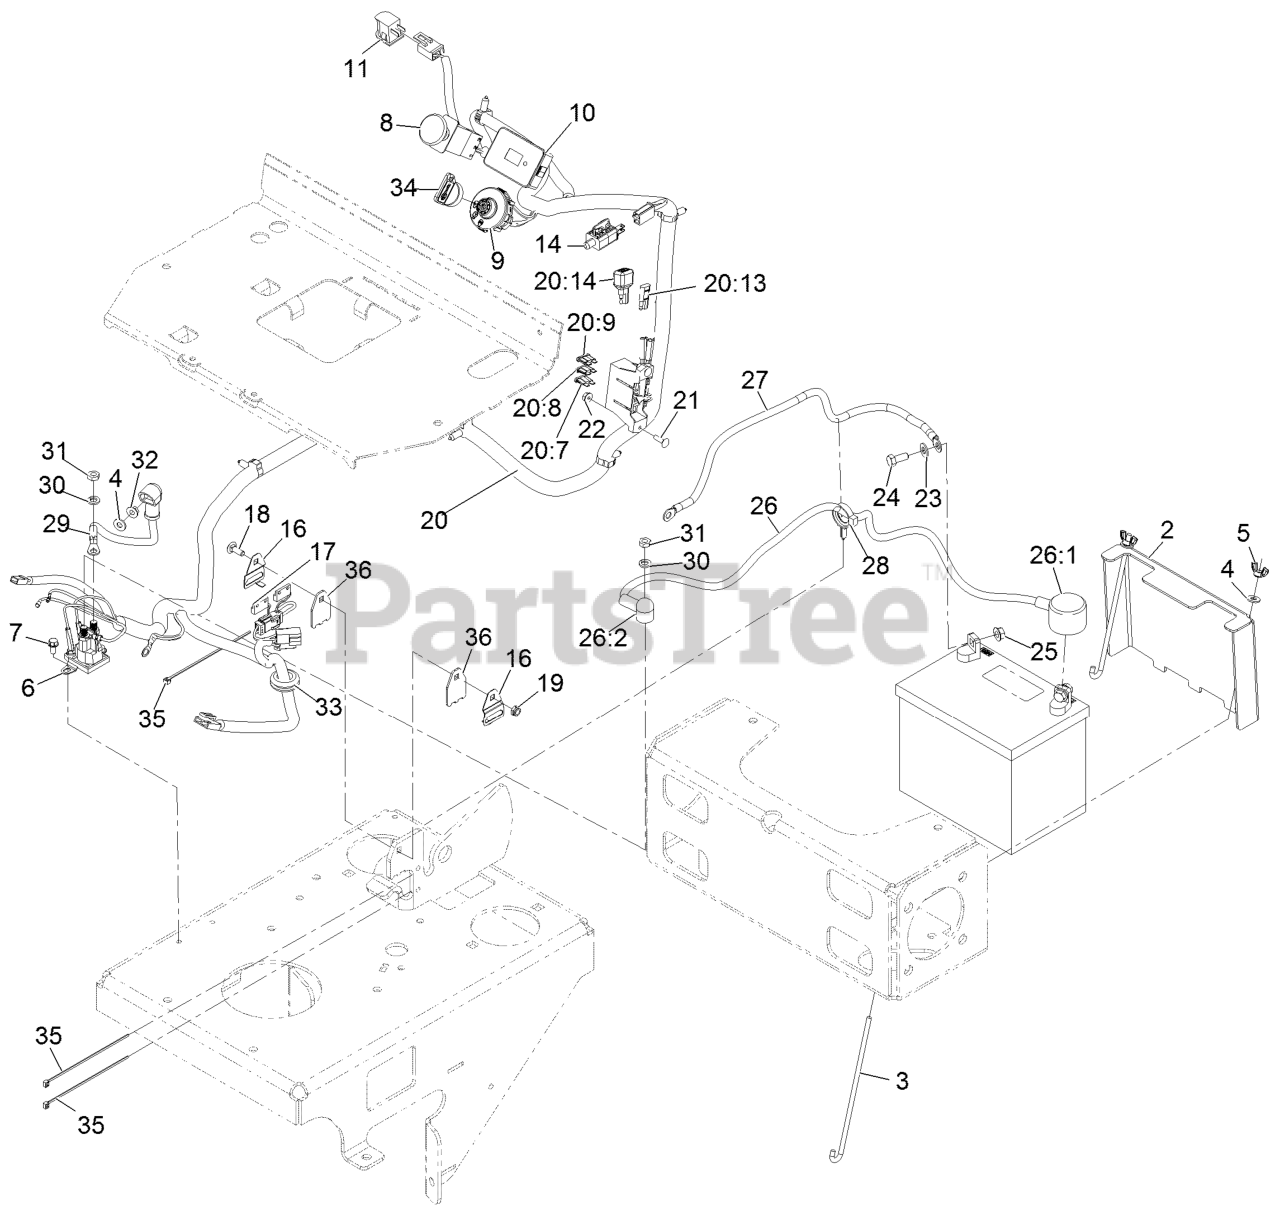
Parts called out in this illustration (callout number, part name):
2	COVER-BATTERY
3	BOLT-HOLDDOWN
4	WASHER-FLAT
5	WINGNUT
6	SOLENOID
7	SCREW-HWH
8	SWITCH-PTO, ON-ON
10	MODULE-HOUR METER
11	SWITCH-BAIL
14	SWITCH-PLUNGER, NC, SPST
16	CLAMP-SWITCH
17	HARNESS-SWITCH, REED
18	BOLT-CARR
19	NUT-LOCK, NI
20:7	FUSE-BLADE, 30 AMP
20:8	FUSE-BLADE, 25 AMP
20:9	FUSE-BLADE, 10 AMP
20:13	CAP-PLUG
21	SCREW-CARR
23	WASHER-PLAIN
24	SCREW-HH
25	NUT-HHF, SMOOTH
26	ASM,POSITIVE BATTERY CABL
26:1	INSULATOR-BATTERY
26:2	INSULATOR-SOLENOID
27	CABLE-BATTERY, NEGATIVE
28	CLAMP-HOSE
29	CABLE-BATTERY, RED
30	WASHER-LOCK
31	NUT-JAM
33	GROMMET
34	KEY-IGNITION
35	TIE-CABLE
36	PLATE-SPACER
